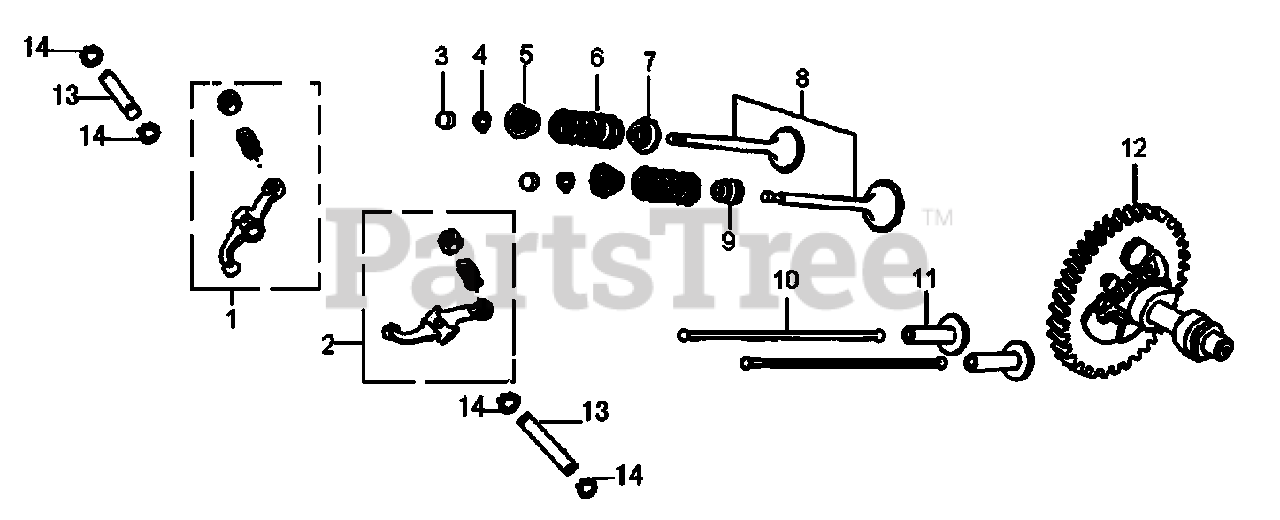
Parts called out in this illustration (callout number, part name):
1	ROCKER ARM ASSY.
2	ROCKER ARM ASSY.
3	ROTATOR,VALVE
4	VALVE LOCKER
5	RETAINER,VALVE SPRING
6	SPRING,VALVE
7	SEAT,VALVE SPRING
8	VALVE ASSY.
9	SEAL,VALVE STEM
11	LIFTER , VALVE
12	CAMSHAFT ASSY
13	ROCKER ARM SHAFT
